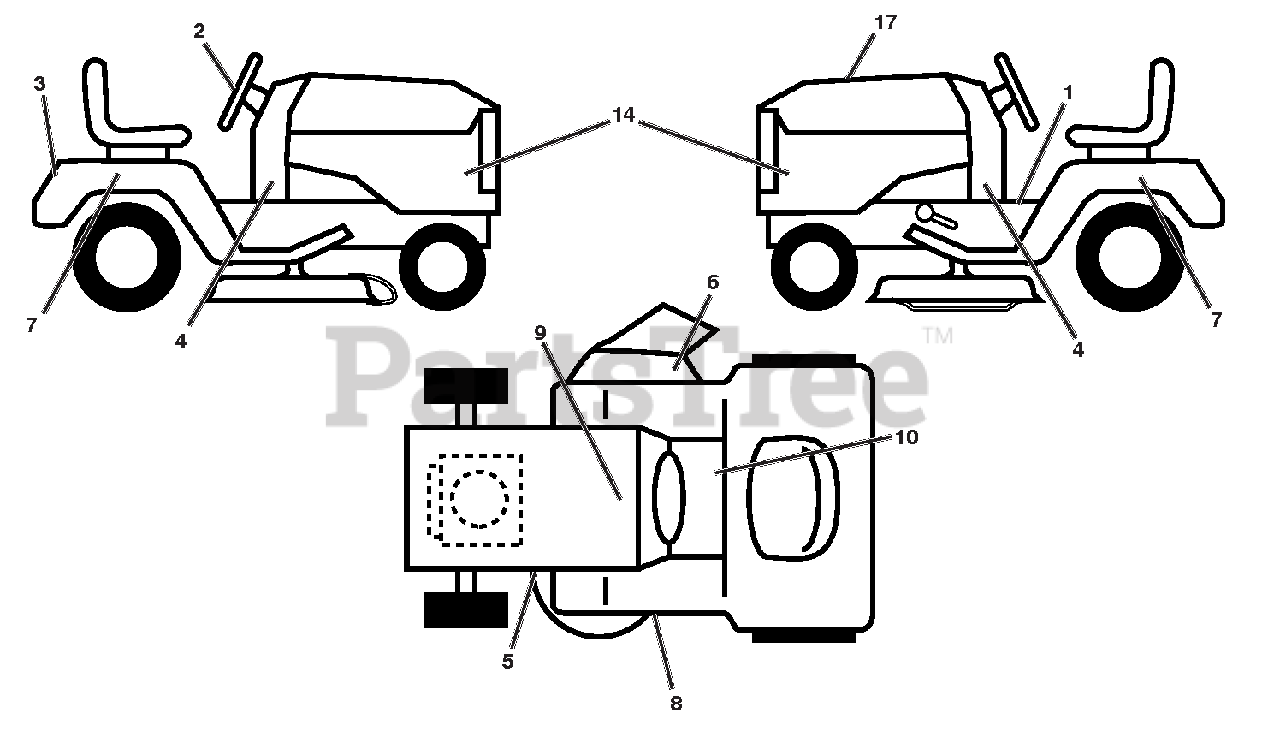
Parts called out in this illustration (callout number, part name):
1	DECAL.WARNING
2	DECAL.WHEEL.STEER.ARIENS
3	DECAL.FENDER.REAR.ARIENS
4	DECAL.DASH
5	DECAL.MOWER.CAUTION.TENSION.AR
6	DECAL.MOWER.WARN.KEEP HAND AWY
7	DECAL.FENDER.SIDE.HYDRO.ARIENS
8	DECAL.MOWER.SCH.48/54.PREM.
9	DECAL.BAT.DAN/POI P/L SYM.WPN
10	DECAL.FENDER
14	DECAL.SDPNL.PWRDBY KOHL.ARIENS
17	DECAL.REPLACEMENT
